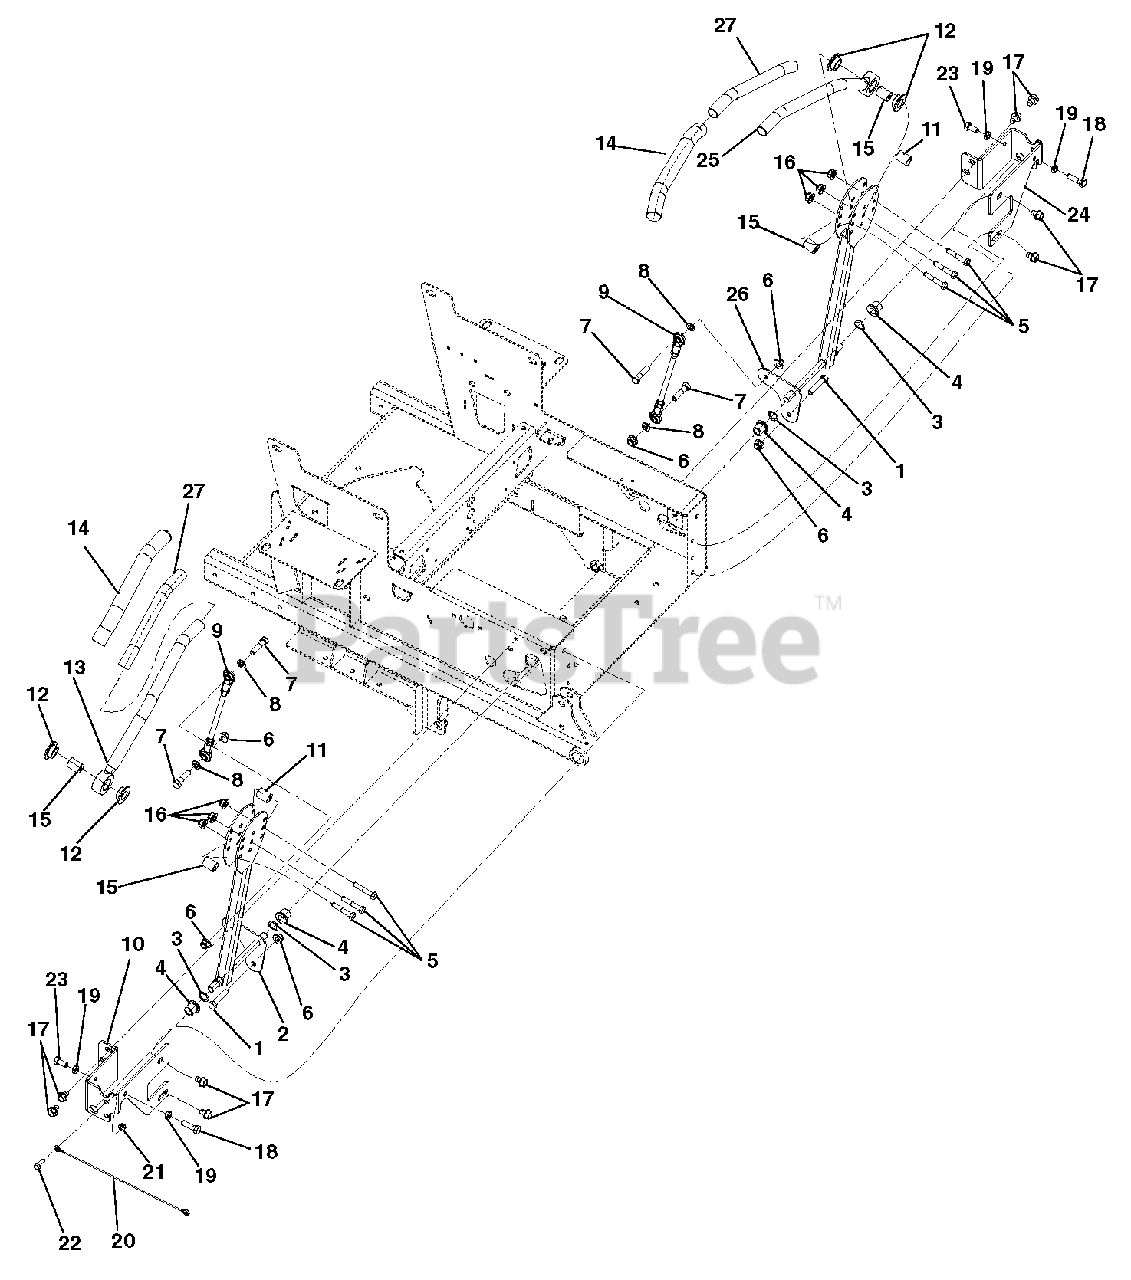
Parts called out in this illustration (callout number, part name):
1	Bolt, Hex .38-16 x 2.00 Full Thread
2	Weldment, Right Hand Control
3	Wave Washer .640 x .875 x .125 Free Height
4	Bushing, Flange .515 x .750 x .745 x 1.00 Nylon
5	Bolt, Hex .31-18 x 1.75 Grade 5
6	Nut, .38-16 Nyloc Flange
7	Bolt, Hex .38-16 x 1.50 Grade 5
8	Washer, Locking .38 x .094 Regular
9	Assembly, Steering Linkage
10	Bracket, Right Hand Steering Stop
11	Eccentric
12	Bushing, Flange .762 x 1.48 x .44 Nylon
13	Handle Weldment Right Hand
14	Grip, Handlebar
15	Spacer, .328 x .76 x 1.01
16	Nut, .31-18 Nyloc Flange
17	Screw, Tapping .38-16 x .50 Hex Washer Head Thread Rolling
18	Bolt, Hex .38-16 x 1.25 Grade 5
19	Nut, Hex-Jam .375-16
20	Cable, 12.0 Lanyard, Nylon
21	Nut, .25-20 Nyloc Flange
22	Bolt, Hex .25-20 x .75 Grade 5
23	Bolt, Hex .38-16 x .75 Grade 5
24	Bracket, Left Hand Steering Stop
25	Weldment, Handle Left Hand
26	Weldment, Left Hand Control
